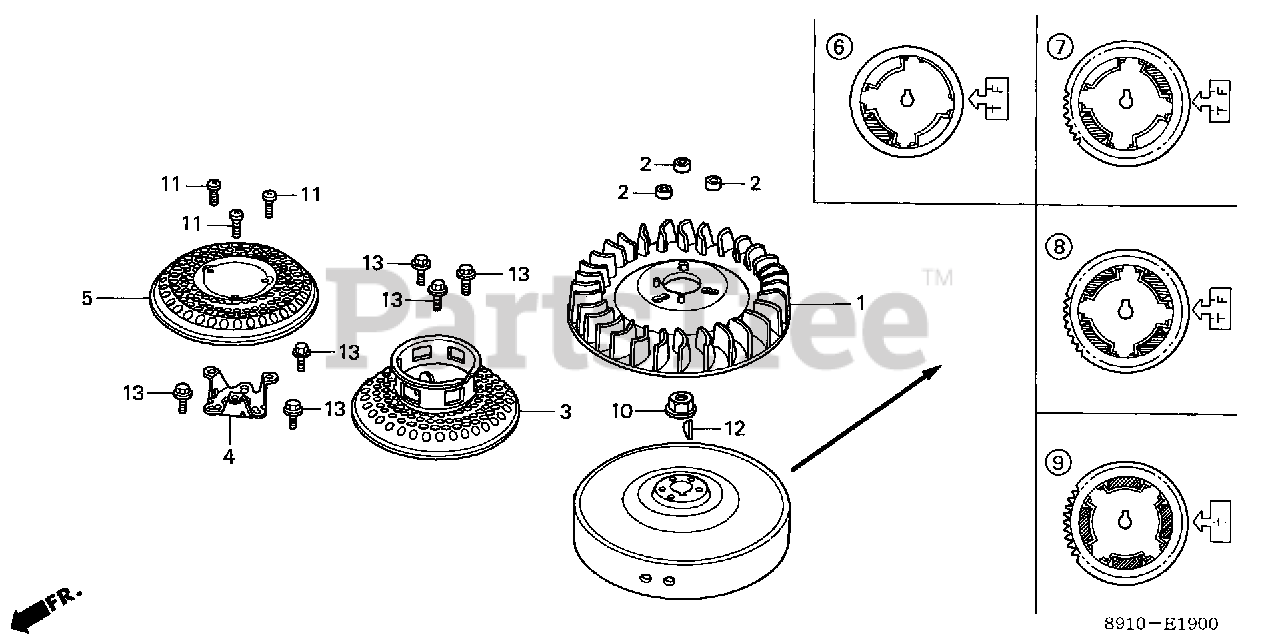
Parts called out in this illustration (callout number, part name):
1	FAN, COOLING
2	COLLAR, FAN
3	PULLEY, STARTER
6	FLYWHEEL (BREAKER)
10	NUT, SPECIAL (16MM)
10	NUT, SPECIAL (16X1.5)
12	KEY, WOODRUFF (25X18)
13	BOLT, FLANGE (6X16)
